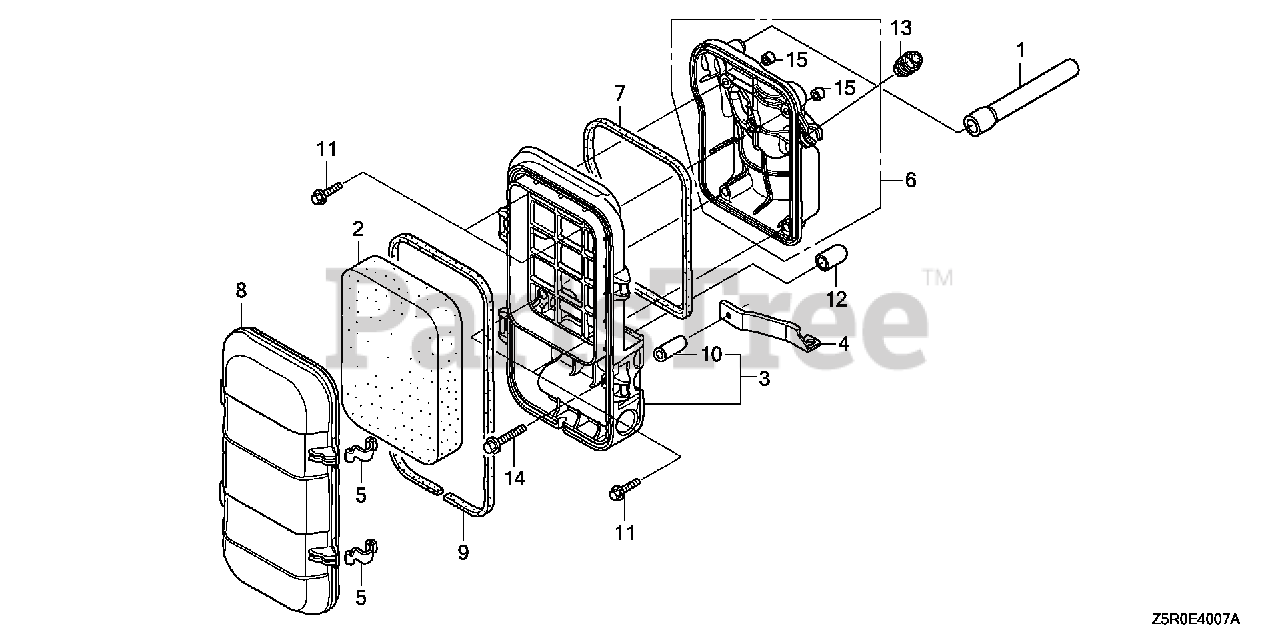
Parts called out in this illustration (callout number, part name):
1	TUBE, BREATHER
2	ELEMENT, AIR CLEANER
3	HOUSING, AIR CLEANER
4	STAY, AIR CLEANER
5	SPRING, AIR CLEANER HOUSING LID
6	BASE, AIR CLEANER
7	SEAL, AIR CLEANER HOUSING
8	COVER, AIR CLEANER
9	SEAL, AIR CLEANER COVER
10	COLLAR, AIR CLEANER
11	BOLT, FLANGE (5X18)
12	CAP, SEALING
13	RUBBER, FUEL (9X15X20)
14	BOLT, FLANGE (6X32)
15	COLLAR, AIR CLEANER
